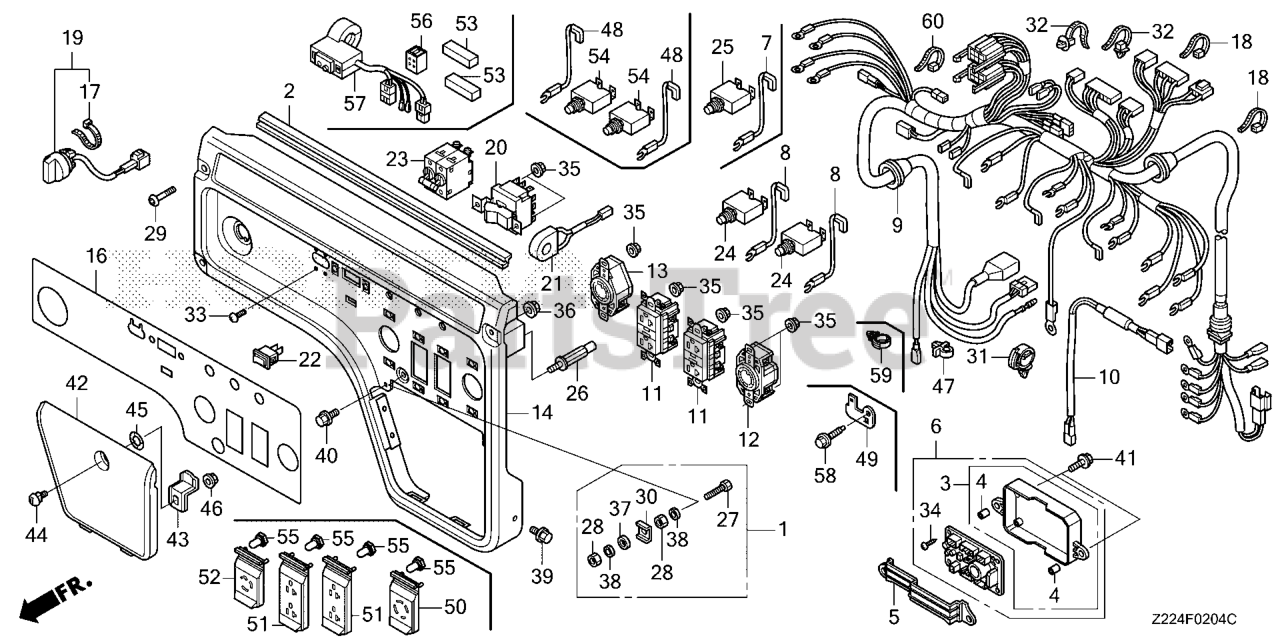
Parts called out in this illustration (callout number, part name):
1	TERMINAL SET, GROUND
2	RUBBER, CONTROL PANEL
3	CASE, AUTOMATIC VOLTAGE REGULATOR (NOT AVAILABLE)
4	COLLAR, AUTOMATIC VOLTAGE REGULATOR CASE (NOT AVAILABLE)
5	COVER, AUTOMATIC VOLTAGE REGULATOR (NOT AVAILABLE)
6	CASE ASSY., AUTOMATIC VOLTAGE REGULATOR (NOT AVAILABLE)
6	COVER ASSY., AUTOMATIC VOLTAGE REGULATOR
8	SUB-WIRE ASSY. (A)
9	WIRE HARNESS ASSY., CONTROL (EB-AG)
11	RECEPTACLE (20A-125V) (GFCI)
12	RECEPTACLE (30A-125/250V)
13	RECEPTACLE (30A-125V)
14	PANEL, CONTROL *R280* (EB-AG) (POWER RED)
16	MARK, PANEL (EB-AG)
17	BAND
19	SWITCH ASSY., ENGINE STOP
20	SWITCH ASSY., VOLT CHANGE
21	SENSOR ASSY. (CT)
22	SWITCH, AUTO-THROTTLE (OTAX)
23	BREAKER, CIRCUIT (21A)
24	PROTECTOR, CIRCUIT (20A)
27	BOLT, HEX. (6X28)
28	NUT, HEX. (6MM)
29	BOLT, DISK (8X22) (TORX)
30	RETAINER (6MM)
31	CLIP, WIRE HARNESS
32	CLIP, HARNESS BAND (145MM) (BLACK)
33	SCREW, PAN (3X5) (NOT AVAILABLE)
34	SCREW, TAPPING (4X10) (PO)
35	NUT, FLANGE (4MM)
36	NUT, FLANGE (6MM)
37	WASHER, PLAIN (6MM)
38	WASHER, SPRING (6MM)
39	BOLT, FLANGE (6X10)
40	BOLT, FLANGE (6X14)
41	BOLT, FLANGE (6X16) Use from Engine SN 2056820.
42	COVER (LOWER)
43	LOCK PLATE, COVER (LOWER)
44	BOLT, MAINTENANCE LID LOCK
45	WASHER, WAVE (12MM)
46	NUT, FLANGE (6MM)
48	SUB-WIRE ASSY. (A)
49	BRACKET, CONNECTOR
50	COVER, RECEPTACLE (30A-125/250V)
51	COVER, RECEPTACLE (20A-125V)
52	COVER, RECEPTACLE (30A-125V)
53	RUBBER, WATERPROOF
54	PROTECTOR, CIRCUIT (30A)
55	COVER, CIRCUIT PROTECTOR
56	LED ASSY., INDICATER
57	RELAY ASSY. (GFCI)
58	BOLT, FLANGE (6X12) (CT200)
59	CLIP, WIRE HARNESS
60	TIE, CABLE (C)
